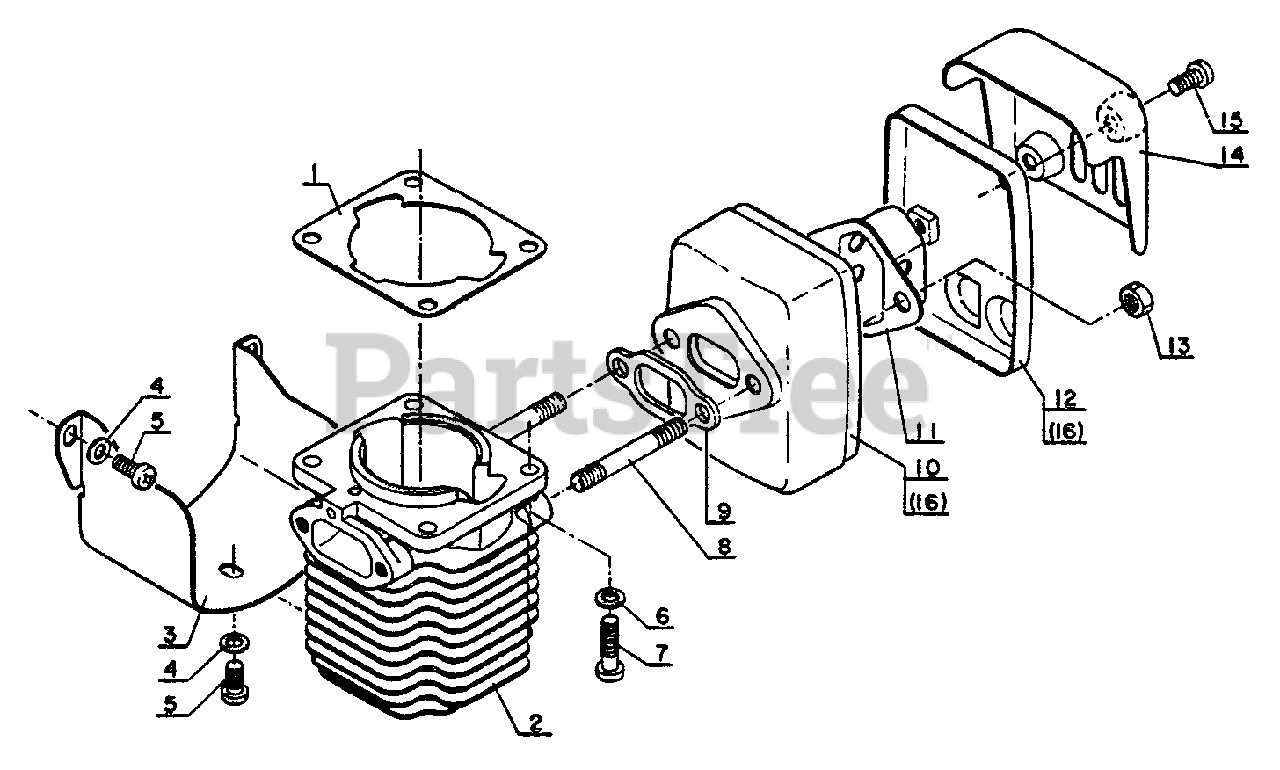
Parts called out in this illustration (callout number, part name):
1	GASKET, CYLINDER
2	CYLINDER
3	SHIELD, CYLINDER
4	WASHER - 4
5	SCREW - 4X8
6	WASHER - 4
7	SCREW - 4X16
8	STUD
9	GASKET, EXHAUST
10	MUFFLER
11	BAFFLE, MUFFLER
12	LID, MUFFLER
14	COVER, MUFFLER
15	SCREW - 4X8
